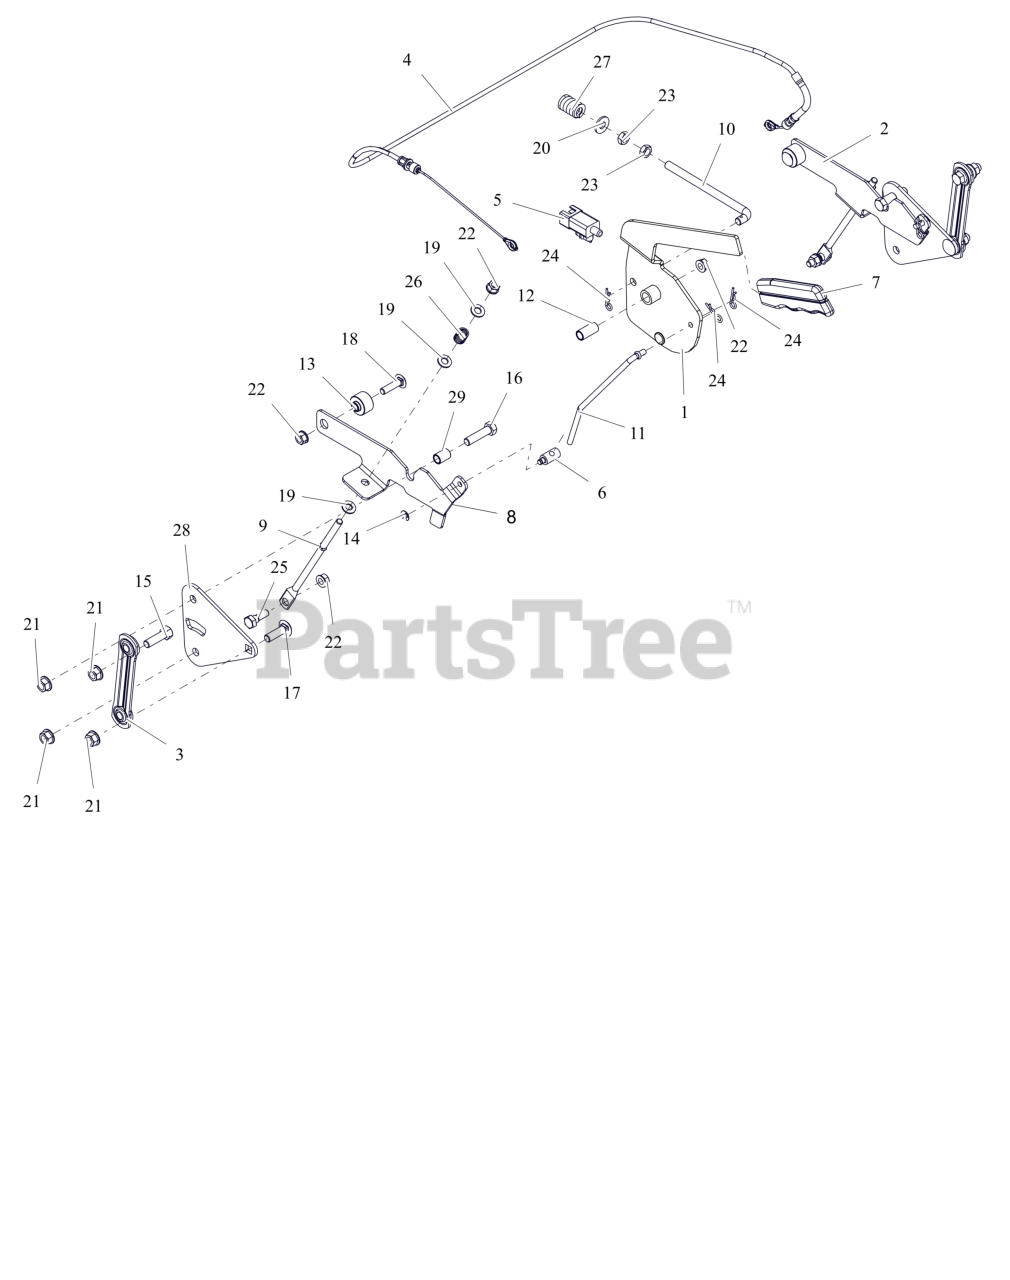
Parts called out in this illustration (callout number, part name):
1	LEVER, PARKING BRAKE
2	ARM, BRAKE - LH (W/PIN)
3	LINK, STAMPED STEERING
4	CABLE, BRAKE - PARKING
5	SWITCH, SNAP IN - N.O./N.O.
6	TRUNION, 1/4-20
7	GRIP, PARKING BRAKE (YELLOW)
8	ARM, BRAKE - RH
9	ROD, LINK - TRANSMISSION BRAKE
10	ROD, OVER CENTER
11	ROD, BRAKE LINK
12	BSHG-SLV .385X.500X1.045
13	SPCR, FLANGE
14	RG-RTNG-EXT .250X.025
15	BLT, HEX .38-16X1.25 G5 ZCC
16	BLT, HEX .38-16X1.50 G5 ZCC
17	BLT,RHSSN .38-16X1.25 G5 ZCC
18	BTL,RHSSN .313-18 X 1.25 G5 ZCC
19	WSHR,FLT .344X.688X.065 ZCC
20	WSHR,FLT .375X.875X.083 ZCC
21	NUT-LK-TOP-FLG .38-16 ZC120
22	NUT-LK-TOP-FLG .312-18 GF ZCC
23	NUT-JAM .375-16 G2 ZCC
24	PIN, HAIR #213 .08X1.19 ZCC
25	BOLT,SHLDR .38X.25 -.31-18X.75
26	SPRING, COMPRESSION
27	SG-COMP .187X.56X1.62
28	PLATE, TRANSAXLE (BLACK)
29	SPCR SLEEVED .385X.500X.718
